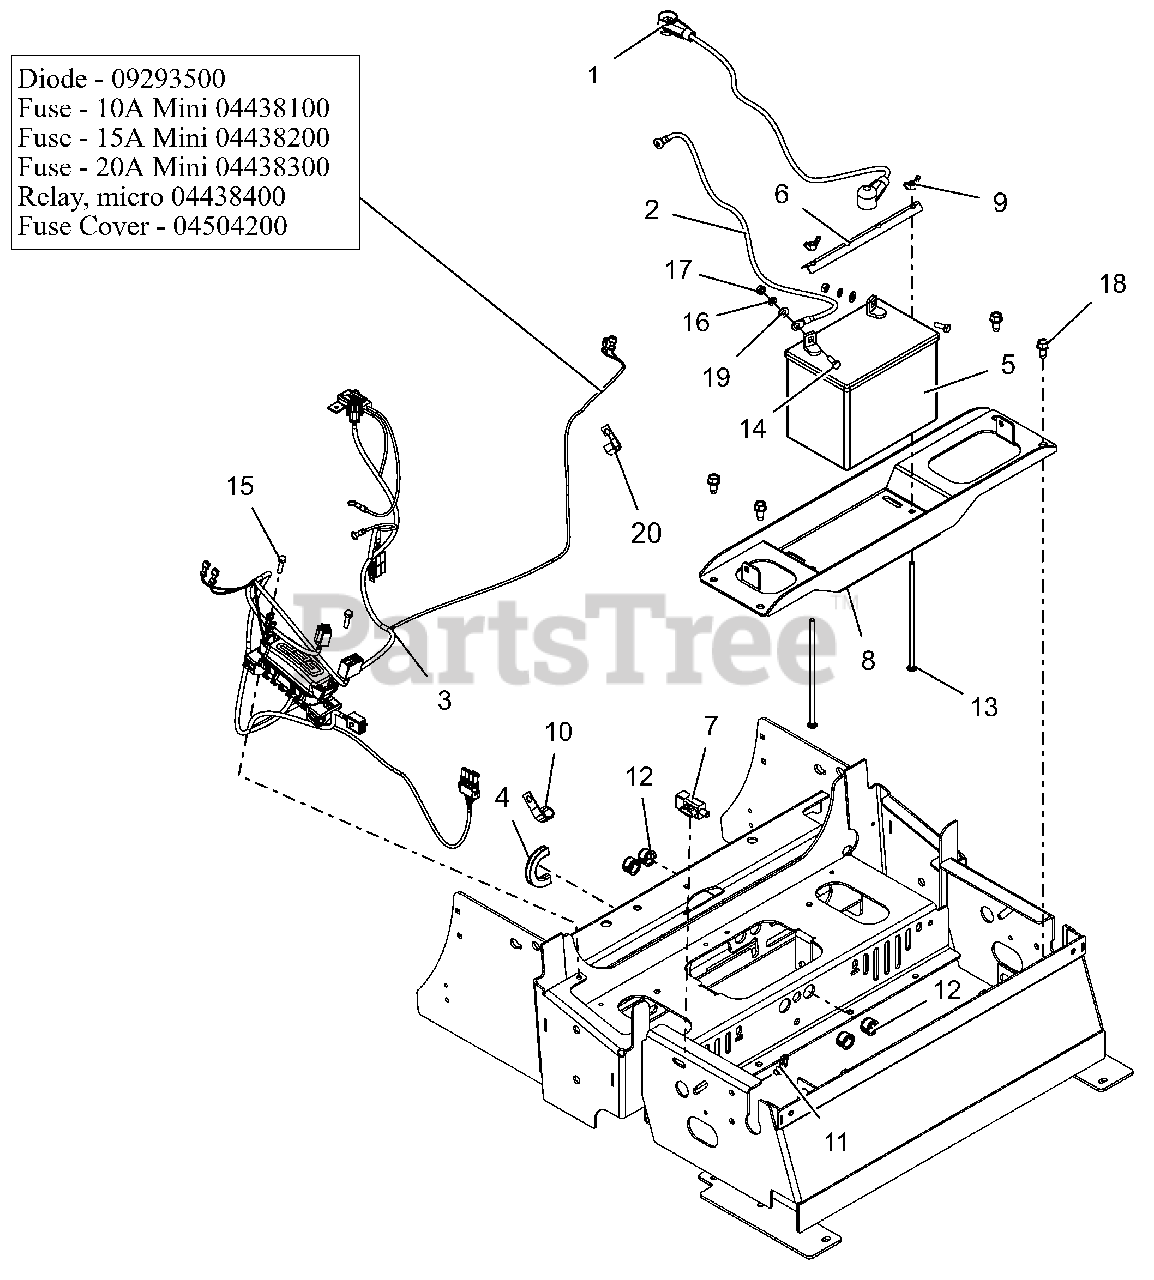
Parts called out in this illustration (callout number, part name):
1	CABLE - POS BATT W/BOOTS 6X35
2	CABLE-NEGATIVE BATTERY 35.00"
3	HARNESS, PT400 WIRING
3	DIODE, CONNECTOR SHELL
3	FUSE,10 AMP MINI-ATC
3	FUSE,15 AMP MINI-ATC
3	FUSE,20 AMP MINI ATC
3	RELAY,MICRO5 TERML W/RESISTOR
3	COVER, HARNESS FUSE/RELAY MOD
4	STRIP, COWL
5	BATTERY, 300 CCA 10U1L
6	HOLD DOWN
7	SWITCH, SNAP IN - N.O./N.O.
8	PT400 GAS BATTERY TRAY - RED
9	NUT-LK WING .250-20 YWZC
11	CABLE TIE W/ TREE (.25 HOLE)
12	BUSH, PANEL SNAP .687X.875X.56
13	BLT-RDHDSQNK .25-20X7.50 GR2YZ
14	@BLT-HEX .25-20X.75 GR5 YWZC
15	@BLT-HEX M6-1.0X25 YWZC
16	@WSHR-LK .25X.062 REG YWZC
17	@NUT-HEX .25-20 YWZC
18	@SCR-TAP .38-16X.75 HWH TR YWZ
19	@WSHR-FL-STL.281X.62X.065 YWZC
